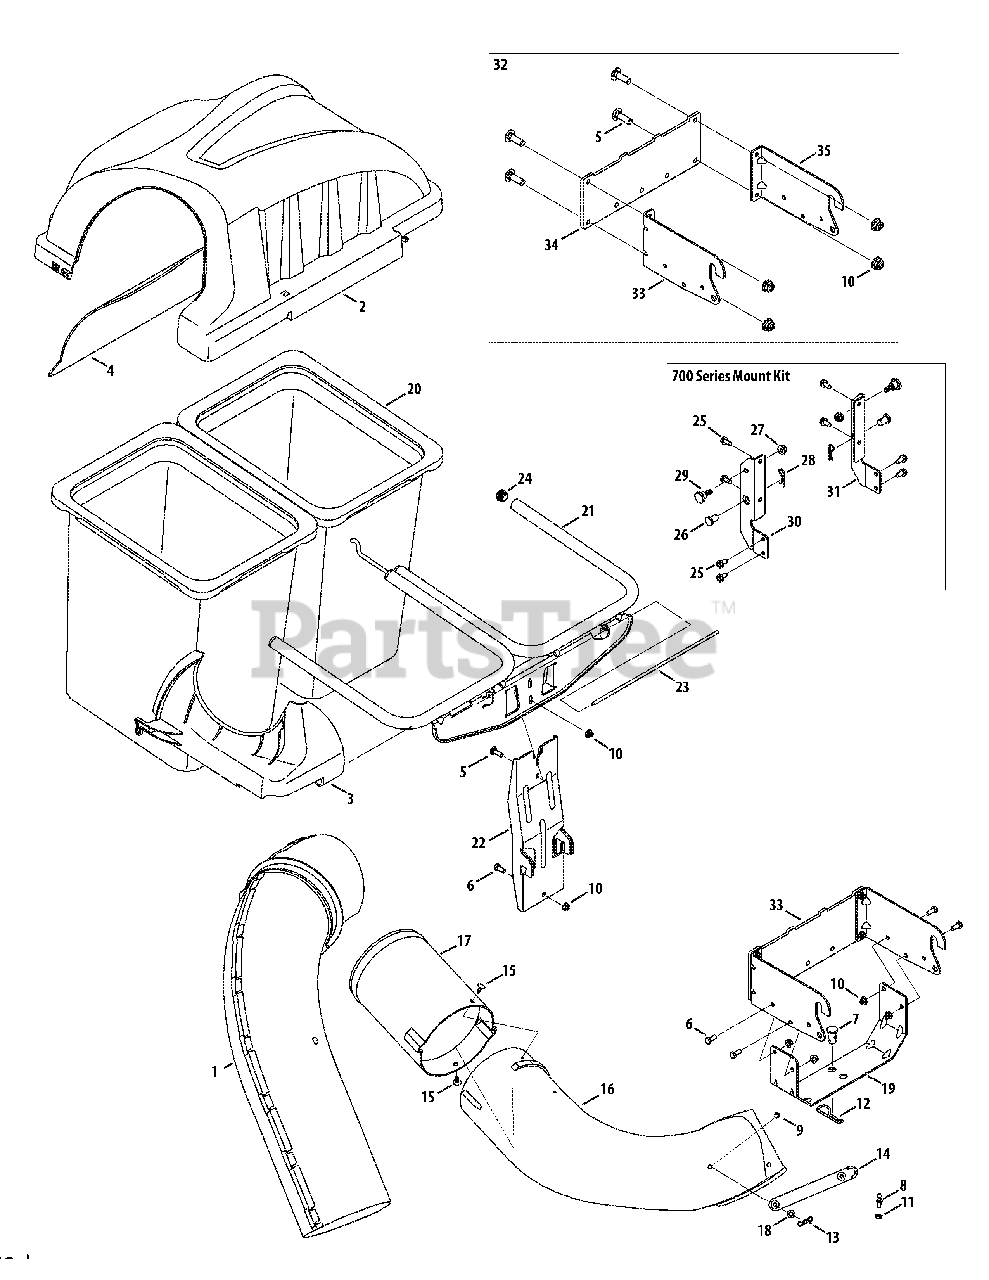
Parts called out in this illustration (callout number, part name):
1	Upper Chute Assembly
2	Double Bagger Cover Assembly
3	Upper Chute Support
4	Bagger Cover Screen
5	Carriage Screw, 5/16-18 x 1.00"
6	Hex Head Screw, 5/16-18 x .75"
7	Clevis Pin, .62" Dia.
8	Grass-catcher Pin, 1/4-20
9	Clevis Pin, 5/16 x .75 Lg.
10	Flange Lock Nut, 5/16-18
11	Flange Lock Nut, 1/4-20
12	Internal Cotter Pin, .148 x 3.00
13	Bow-Tie Cotter Pin, 72
14	Chute Strap, 6.00 Lg.
15	Ratchet Clip, .250
16	Discharge Chute Elbow, 38"/42"
17	Bagger Chute Adapter, 7 In.
18	Flat Washer, .344 x .62 x .033
19	Universal Bracket Support, RT-99/
20	Grass-bag Assembly
23	Cover Hinge Pin
25	Tap Screw, 5/16-18 x .750
26	Clevis Pin, .50 x .78 Lg.
27	Flange Lock Nut, 3/8-16
28	Click Pin, .092 x 1.64 Lg.
29	Shoulder Screw, .625 x .412
32	Hitch Bracket Assembly
33	Hitch Bracket, RH
34	Rear Attachment Bracket
35	Hitch Bracket, LH
